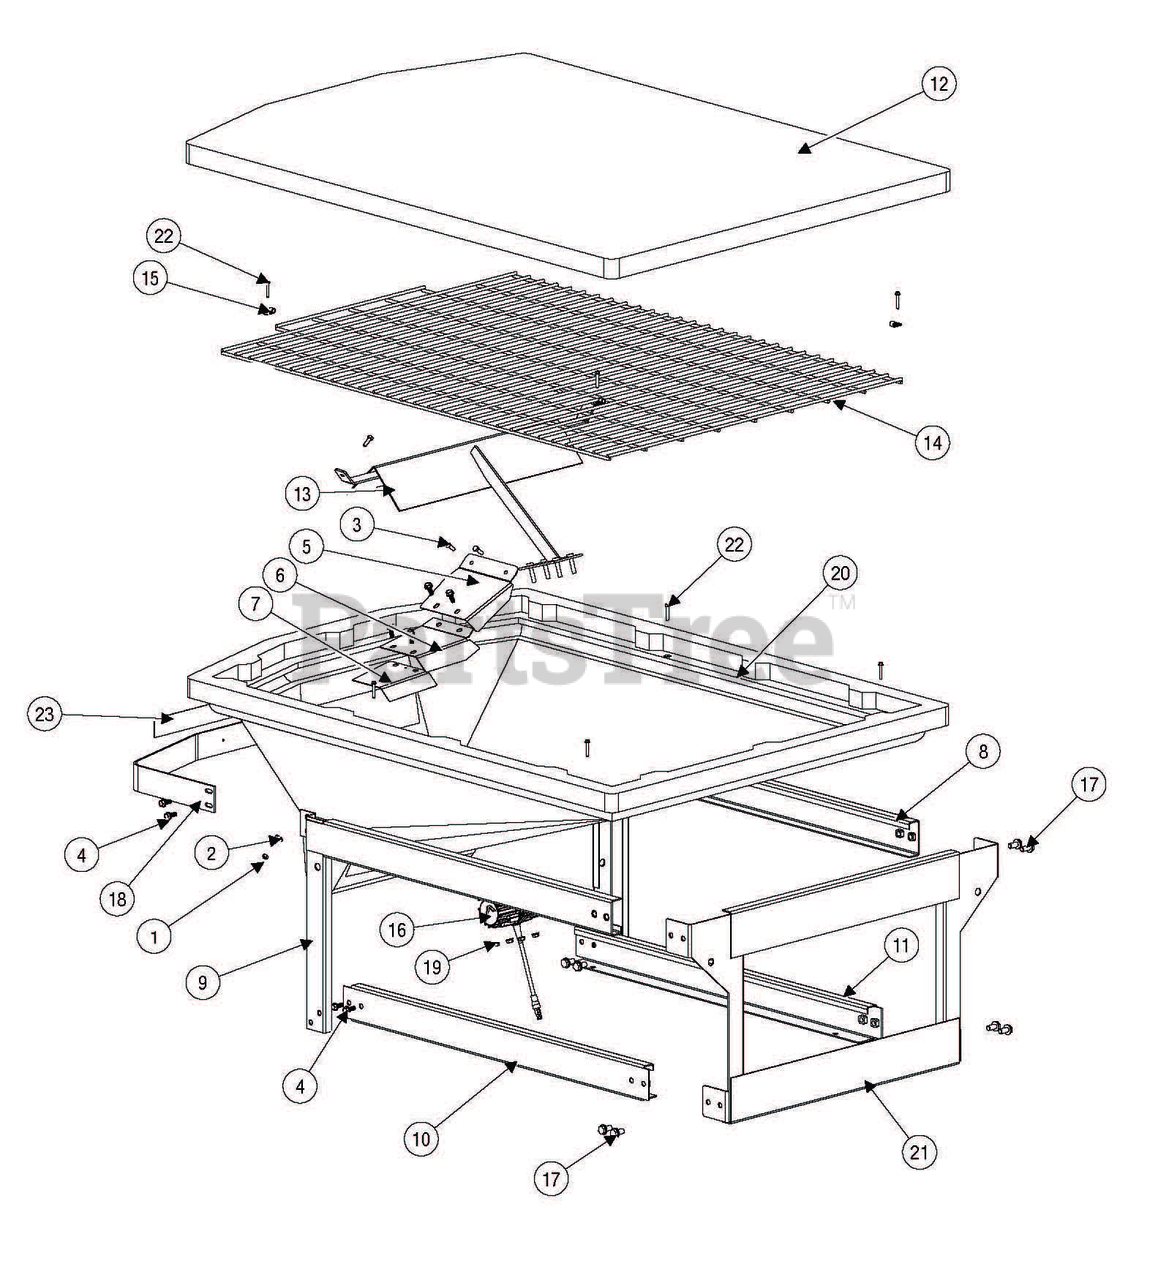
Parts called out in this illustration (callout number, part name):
5	MAIN BAFFLE
6	SECONDARY BAFFLE
7	THIRD BAFFLE
8	FRAME WELDMENT, RIGHT 46-3/4 X 22-3/8
9	FRAME WELDMENT, LEFT, 46-3/4 X 22-3/8
10	LOWER RAIL, RIGHT 44-3/8 X 3-3/4
11	LOWER RAIL, LEFT 44-3/8 X 3-3/4
12	TARP KIT, SP-3000
13	INVERTED V PRO
14	TOP SCREEN 59 X 42
15	CLAMP, 5/16 RUBBER COATED
16	VIBRATOR, DC 200
18	HOPPER APRON PRO TRUCK
20	HOPPER 13.5 CU. FT. YELLOW
21	FRONT FRAME WELDMENT PRO TRUCK
23	CONSPICUITY TAPE
